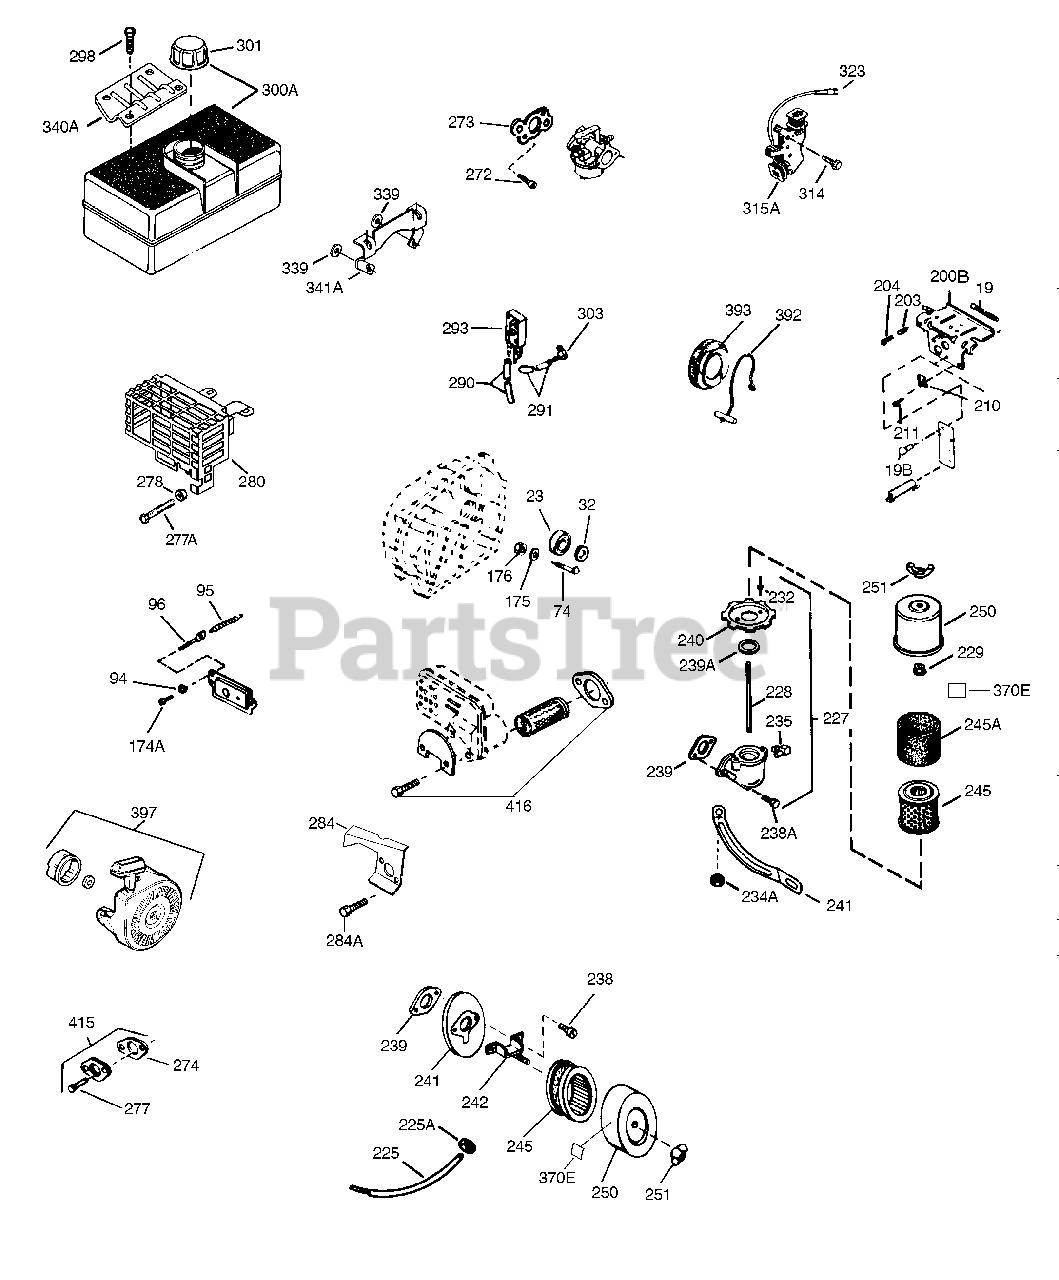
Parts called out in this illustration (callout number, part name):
94	Lock Nut, 10-32
95	Extension Spring
96	R.P.M. Adjusting Bolt
129	Screw, 5/16-18 x 1-3/4"
131A	Screw, 5/16-18 x 5/8"
238	Screw, 10-32 x 1/2"
239	* Air Cleaner Gasket
240	Air Cleaner Body
242	Air Cleaner Bracket
245	Air Filter (Paper) also available in Packaged Part #740027B
250	Air Cleaner Cover
251	Wing Nut, 1/4-20
264	Screw, 1/4-20 x 5/8"
277	Screw, 5/16-18 x 3-3/16"
290	Fuel Line
291	Fuel Line (8.62")
298	Screw, 1/4-15 x 3/4"
301	Fuel Cap (Red)
306	Oil Fill Plug Gasket
340A	Fuel Tank Bracket
341A	Fuel Tank Bracket
